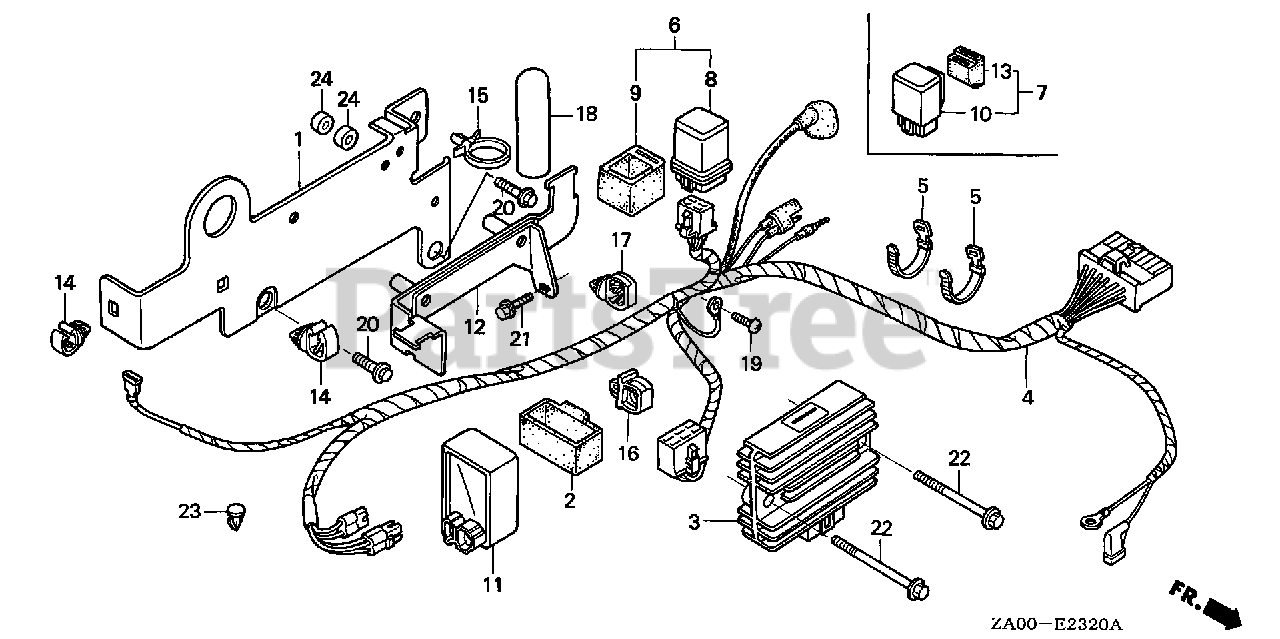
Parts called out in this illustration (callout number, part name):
1	HOOK, ENGINE
2	CUSHION, IGNITION CONTROL MODULE (CDI)
3	RECTIFIER ASSY., REGULATOR
4	WIRE HARNESS ASSY. (10A)
5	BAND, WIRE
6	RELAY ASSY., CONTROL (10A)
6	RELAY, CONTROL
7	RELAY ASSY., CONTROL (10A)
8	RELAY ASSY., CONTROL (10A)
8	RELAY, CONTROL
9	SUSPENSION, CONTROL RELAY
10	RELAY (10A)
11	ALERT UNIT
12	BRACKET, ALERT UNIT
13	SUSPENSION, STARTER RELAY (TATEISHI)
14	CLIP, WIRE HARNESS
15	CLIP, WIRE HARNESS
17	CLIP, HARNESS (10MM)
18	TUBE, CORD (22MM)
19	SCREW, PAN (5X12)
20	BOLT, FLANGE (8X20)
21	BOLT, FLANGE (6X12)
22	BOLT, FLANGE (6X45)
